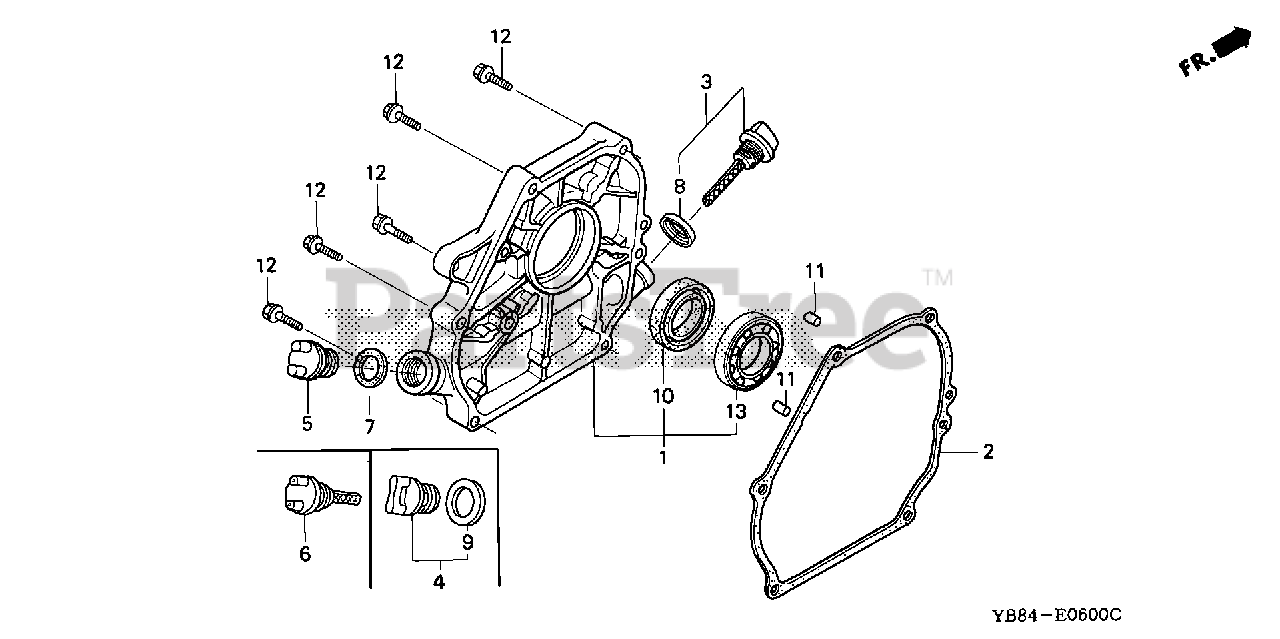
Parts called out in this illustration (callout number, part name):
1	COVER ASSY., CRANKCASE
2	GASKET, CASE COVER (NON-ASBESTOS)
3	CAP ASSY., OIL FILLER (GRAY)
4	CAP ASSY., OIL FILLER
8	GASKET, OIL FILLER CAP
9	GASKET, OIL FILLER CAP
10	OIL SEAL (25X41X6) (NOK)
11	PIN, DOWEL (8X14)
12	BOLT, FLANGE (8X32)
13	BEARING, RADIAL BALL (6205)
